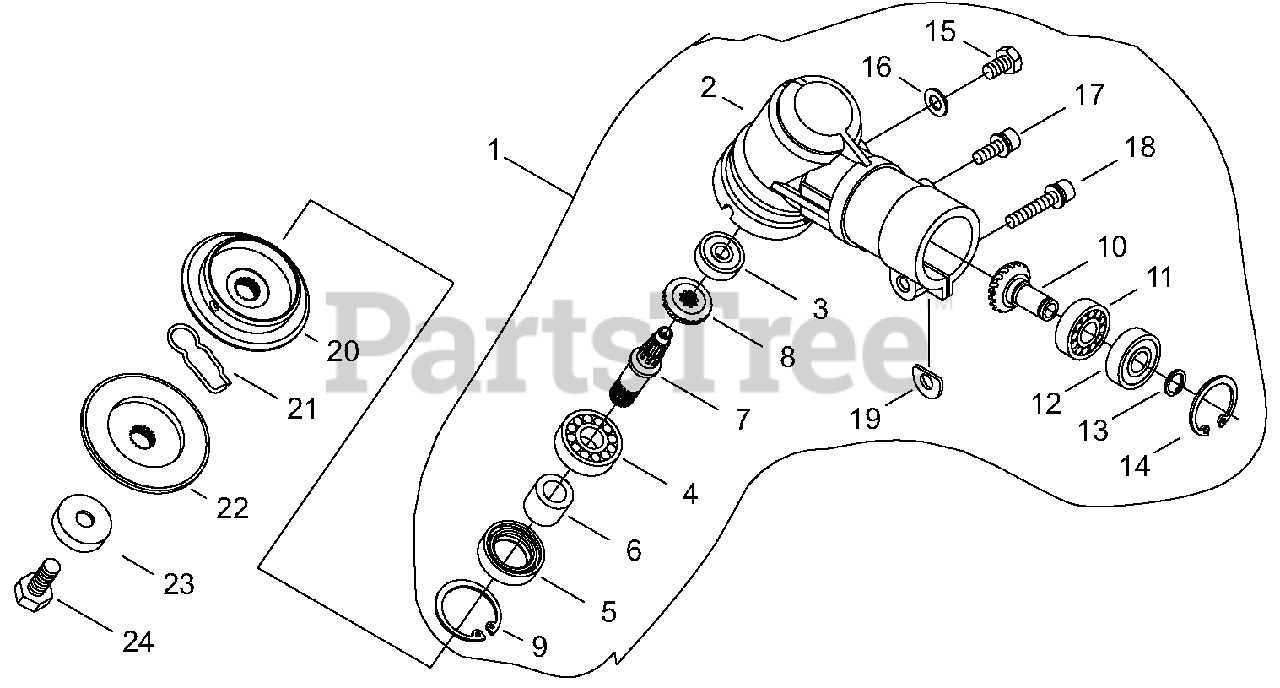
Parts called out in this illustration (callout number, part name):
1	GEAR CASE ASSY
2	CASE, GEAR
3	BEARING, BALL - 6000
4	BEARING, BALL - 6202
5	SEAL, OIL
6	COLLAR
7	GEAR - SHAFT
8	GEAR - BEVEL
9	RING, RETAINING - 35
10	GEAR - SHAFT
11	BEARING, BALL - 6001
12	BEARING, BALL - 6001ZZ
13	RING, RETAINING
14	RING, RETAINING - 28
15	BOLT - 6X10
16	WASHER
17	BOLT - 6X14
18	SCREW - 6X28
19	SHIM
20	ADAPTOR, BLADE - UPPER
21	CLIP
22	ADAPTOR, BLADE - LOWER
23	GUARD
24	BOLT - 10 -- LEFT HAND
